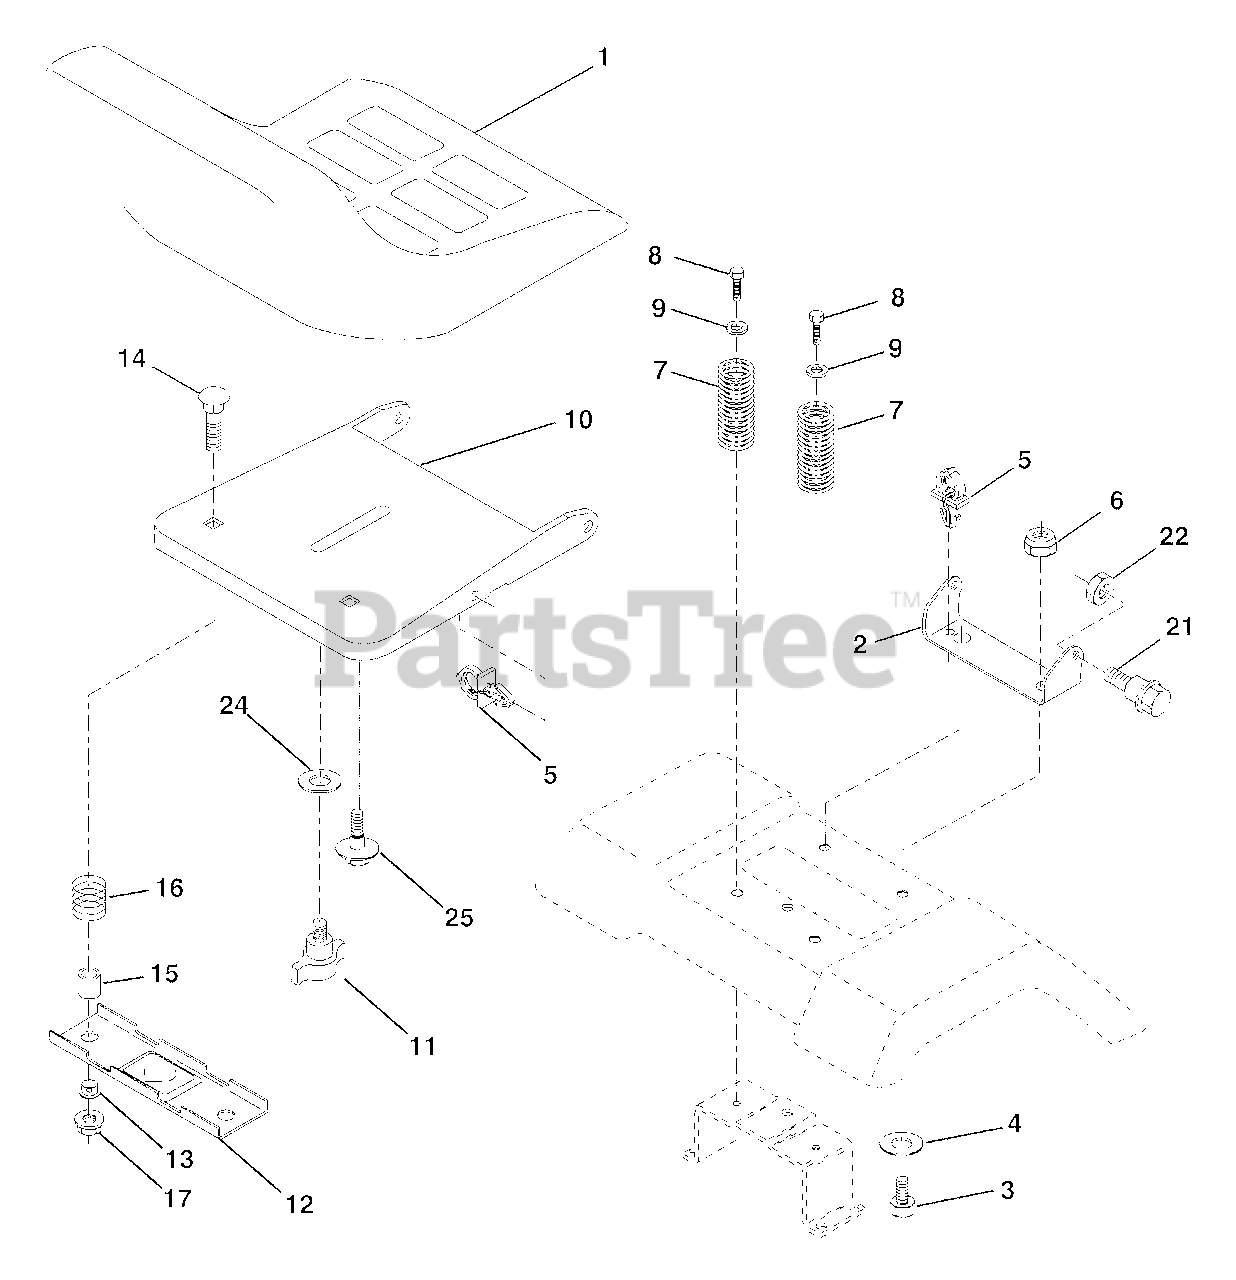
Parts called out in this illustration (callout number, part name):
1	Seat
2	Bracket Pivot Seat 8 720
3	Bolt Fin Hex 3/8-16 x 1
4	Washer Flat 13/32 x 1.0 x 10 Ga.
5	Clip Push-In
6	Nut Hex w/Ins. 3/8-16 unc
7	Spring Seat Cprsn 2 250 Blk Zi
8	Screw 3/8-16 x 1
9	Washer 13/32 x 1.0 x 14 Ga.
10	Pan Seat
12	Bracket Mounting Switch
13	Bushing Snap Blk Nyl 50 Id
14	Bolt Rdhd Sqnk 1/4-20 x 1-1/2
15	Spacer Split 28 x .88 Zinc
16	Spring Cprsn Plate
17	Nut Lock 1/4 Lge Flg Gr. 5 Zinc
21	Bolt Shoulder 5/16-18 unc
22	Nut Hex Lock W/Ins 5/16-18
24	Washer 7/32 x 1-3/16 x 12 Ga.
25	Bolt Shoulder 5/16-18 x .62
